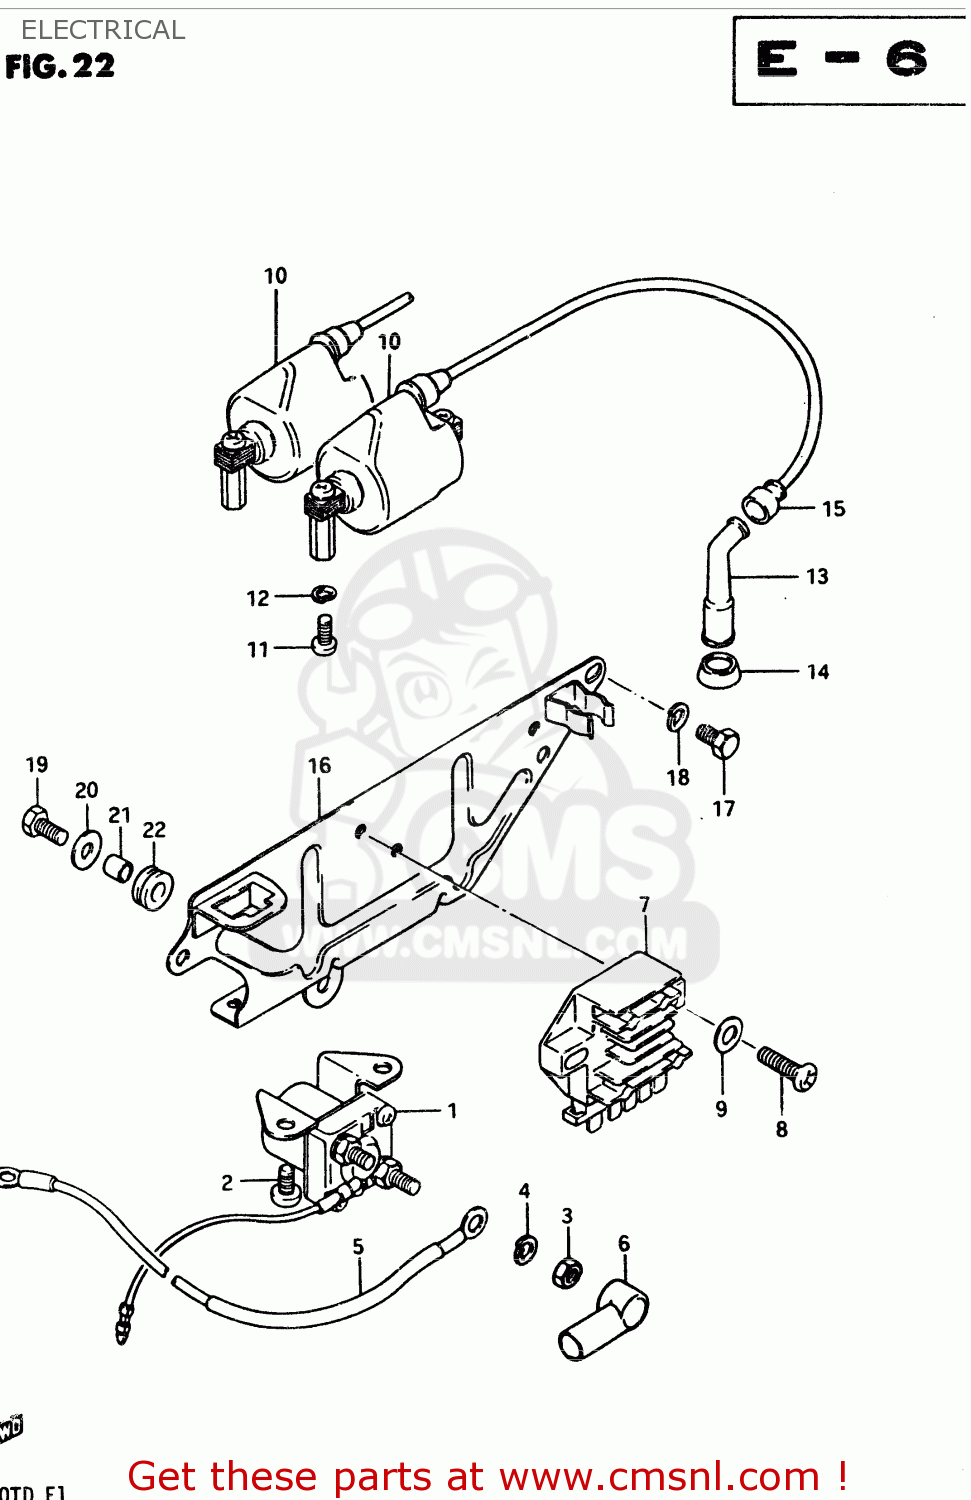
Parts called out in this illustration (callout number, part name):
1	RELAY ASSY,STARTING MOTOR
2	SCREW
3	NUT 6MM
4	LOCK WASHER
5	CORD,BATTERY MINUS
6	CAP,STARTER RELAY
7	RECTIFIER ASSEMBLY
8	SCREW
9	WASHER
10	COIL ASSEMBLY,IGNITION
11	SCREW
12	LOCK WASHER
13	CAP ASSY,SPARK PLUG
14	SEAL,SPARK PLUG
15	SEAL,SPARK PLU
16	HOLDER COMP,ELECTRONIC PARTS
17	BOLT
18	LOCK WASHER
19	BOLT
20	WASHER
21	SPACER (6.1X8X9.5)
22	CUSHION
